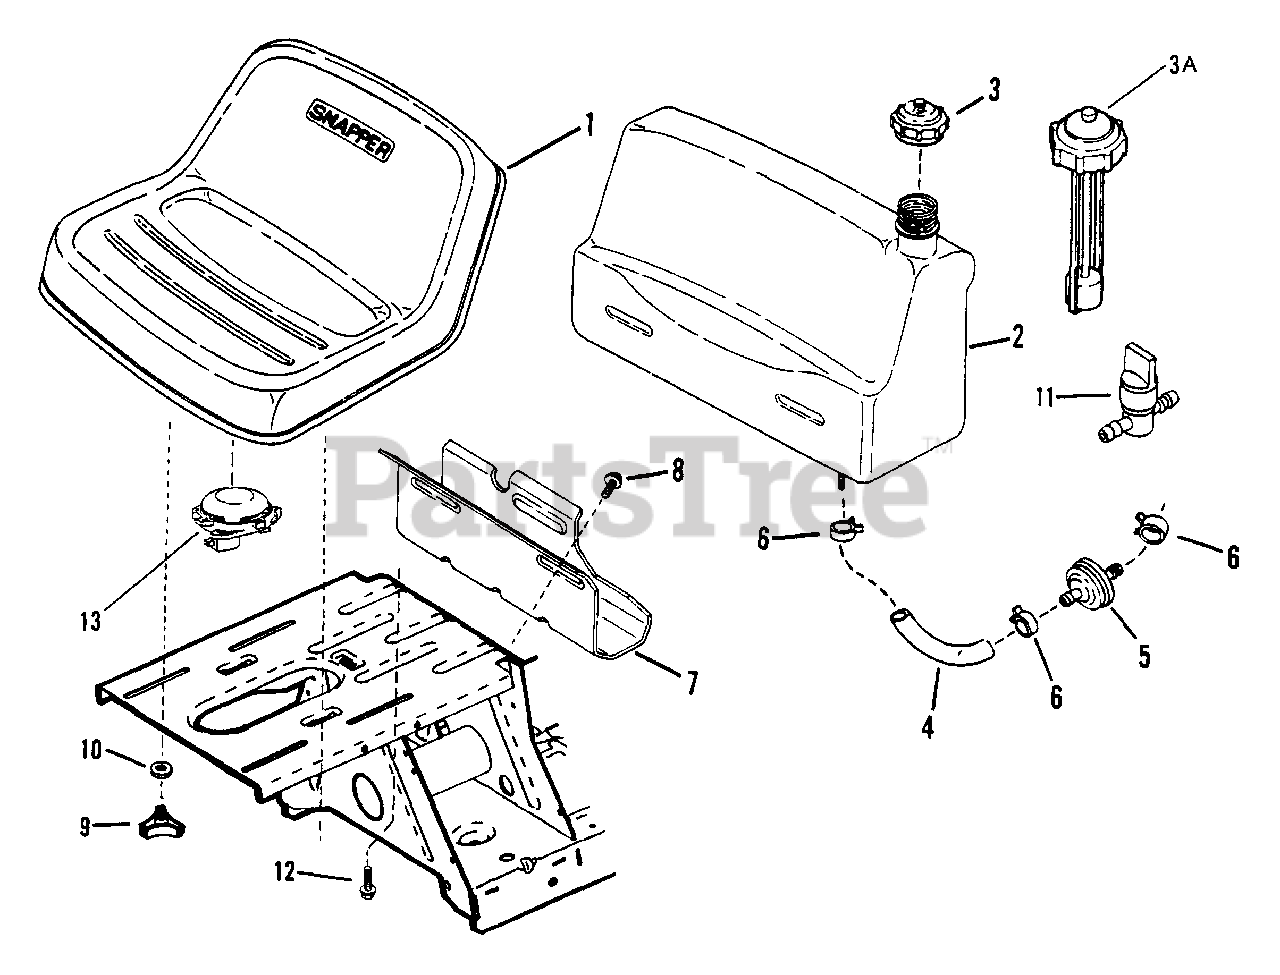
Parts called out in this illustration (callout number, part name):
1	SEAT, Operator (Mid Back)
2	ASSEMBLY, Fuel Tank
3	CAP, Fuel Tank
3A	CAP, Fuel Tank With Gauge
4	HOSE, Fuel (7" Long)
5	FILTER, Fuel (In-Line)
6	CLAMP, Fuel Line
7	BRACKET, Fuel Tank (Rear)
8	SCREW, 5/16-18 x 5/8" Self-Tapping
9	KNOB, Seat Adjusting
10	SPACER, 5/16
11	VALVE, Fuel Shut-Off
12	BOLT, 5/16-18 x 1/2" Hex Flange Lock
13	SWITCH, Seat
